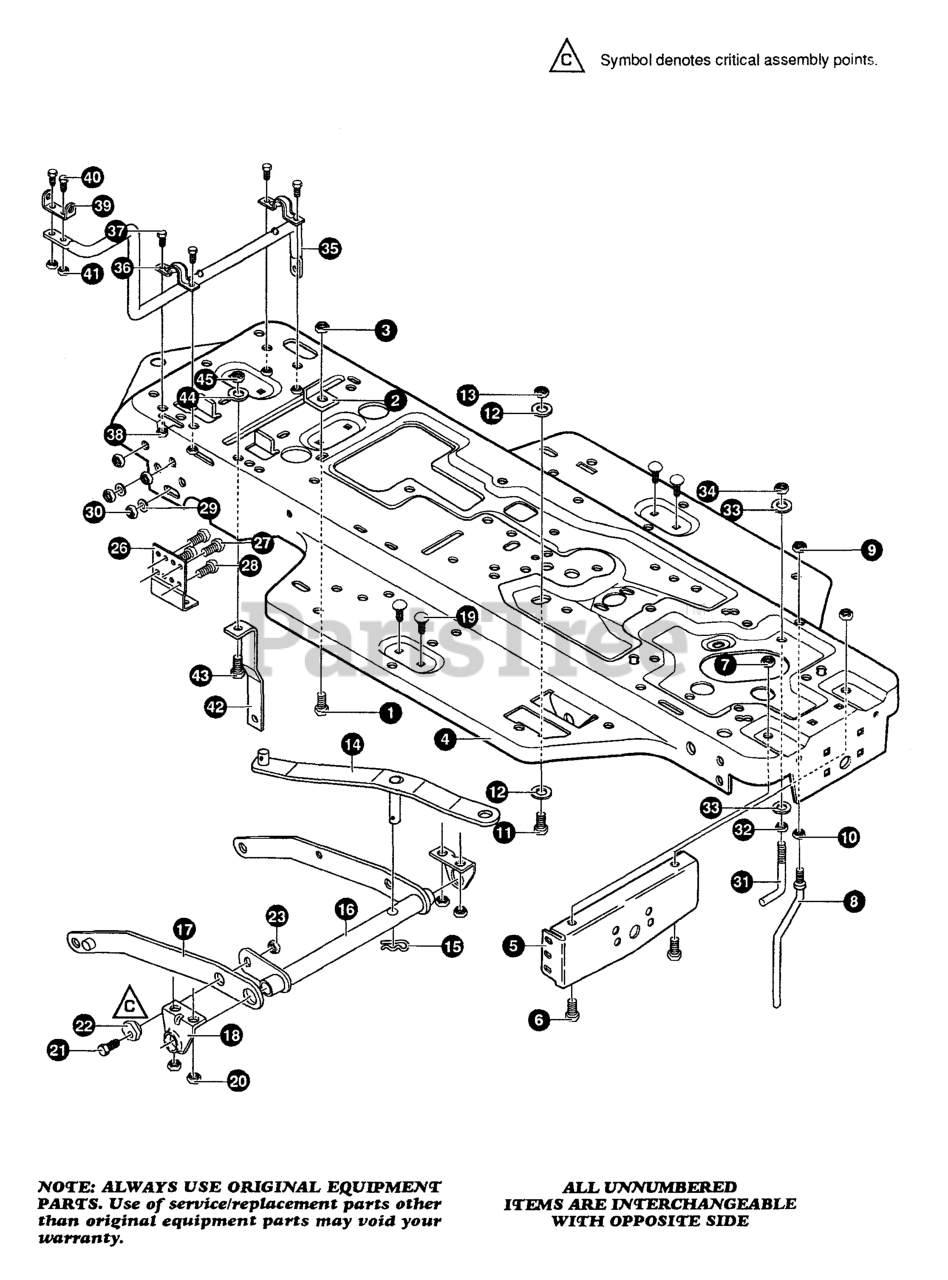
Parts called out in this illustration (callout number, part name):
1	SCREW, 1/4-20 X .75
2	CABLE RETAINING BRACKET
3	NUT, 1/4-20
3	FRAME, MAIN
5	BRACKET, SUPPORT, FRONT
6	SCREW, 5/16-18 x 1.00
7	NUT, 5/16-18
8	GUIDE, BELT
9	NUT, 3/8-16
10	NUT, 3/8-16
11	SCREW, 3/8-16 X 1.25
12	WASHER, FLAT .406 X .81 X .065
13	NUT, 3/8-16
14	STRAP ASSEMBLY, PTO
15	PIN, HAIR
16	LIFT ASSEMBLY, LH
17	LIFT ASSEMBLY,RH
18	BRACKET, REAR HANG
19	BOLT, 5/16-18 X 1.00
20	NUT, 5/16-18
21	SCREW, 5/16-18 x 1.00
22	NUT, ADJUST
23	NUT, 5/16-18
26	BRACKET, TRANSAXLE
27	SCREW, 5/16-18 x 0.75
28	SCREW, 5/16-18 x 1.50
29	WASHER, FLAT .330 X .75 X .1793
30	NUT, 5/16-18
31	BELT GUIDE
32	NUT, 5/16-18
33	WASHER, FLAT .344 X .69 X .065
34	NUT, 5/16-18
35	LEVER, SHIFT LOWER
36	CLAMP.625 DIA
37	SCREW, 5/16-18 x 0.75
38	NUT, 5/16-18
39	BRACKET, PIVOT SHIFT LEVER
40	SCREW, 1/4-20 x .75
41	NUT, 1/4-20
42	BRACKET, STABILIZER
43	SCREW, 5/16-18 x 0.75
44	WASHER, .328 X .60 X .09
45	NUT, 5/16-18
